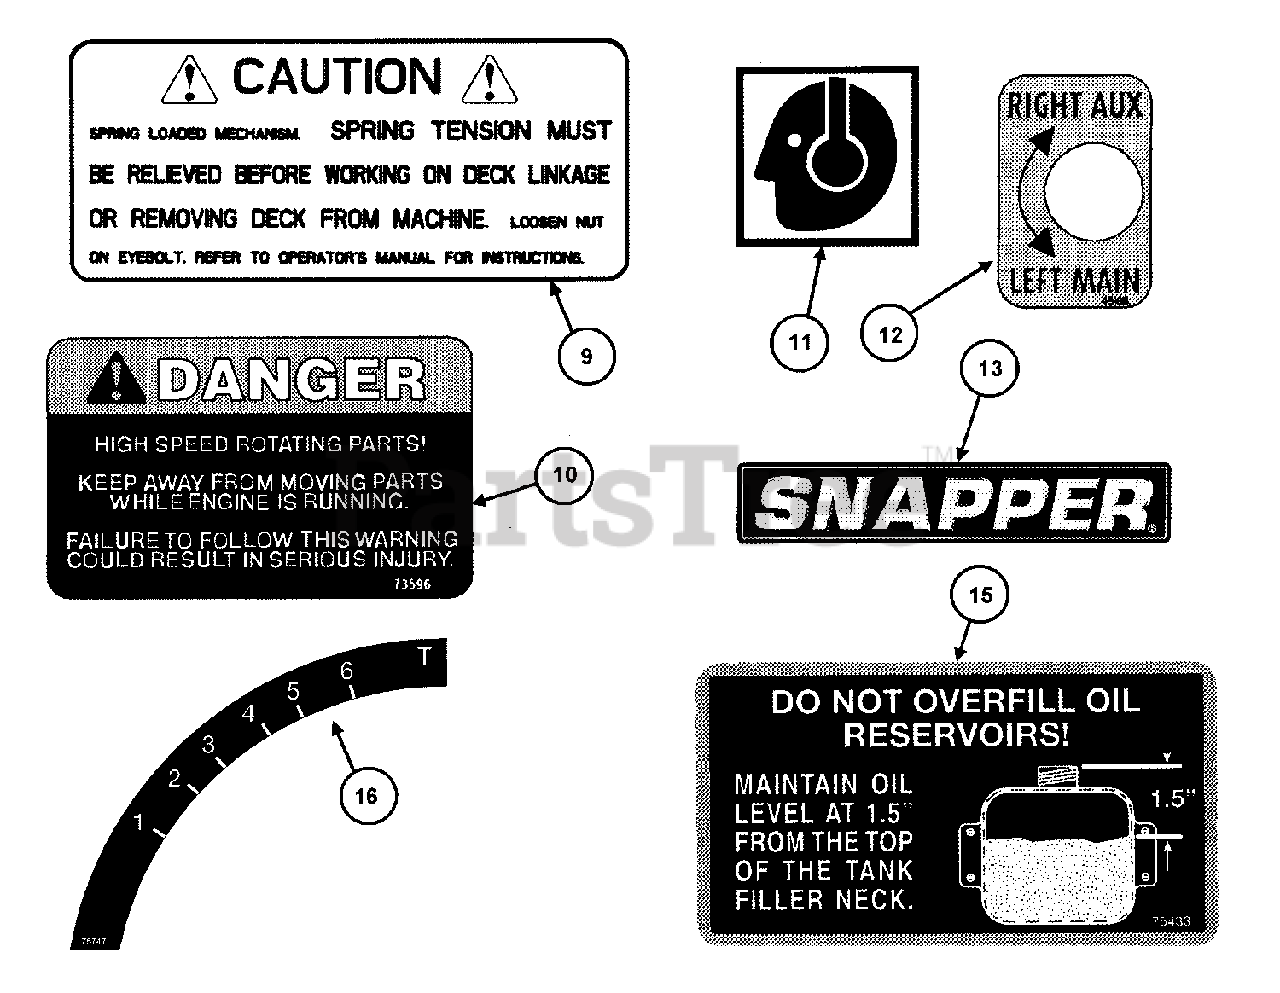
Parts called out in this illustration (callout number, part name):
9	DECAL, Caution (Spring Mechanism)
10	DECAL, Warning
11	DECAL, Ear Protection
12	DECAL, Tank Selector
13	DECAL, SNAPPER (14.56" long)
15	DECAL, Oil Reservoir Overfill Warning
16	DECAL, Detent
